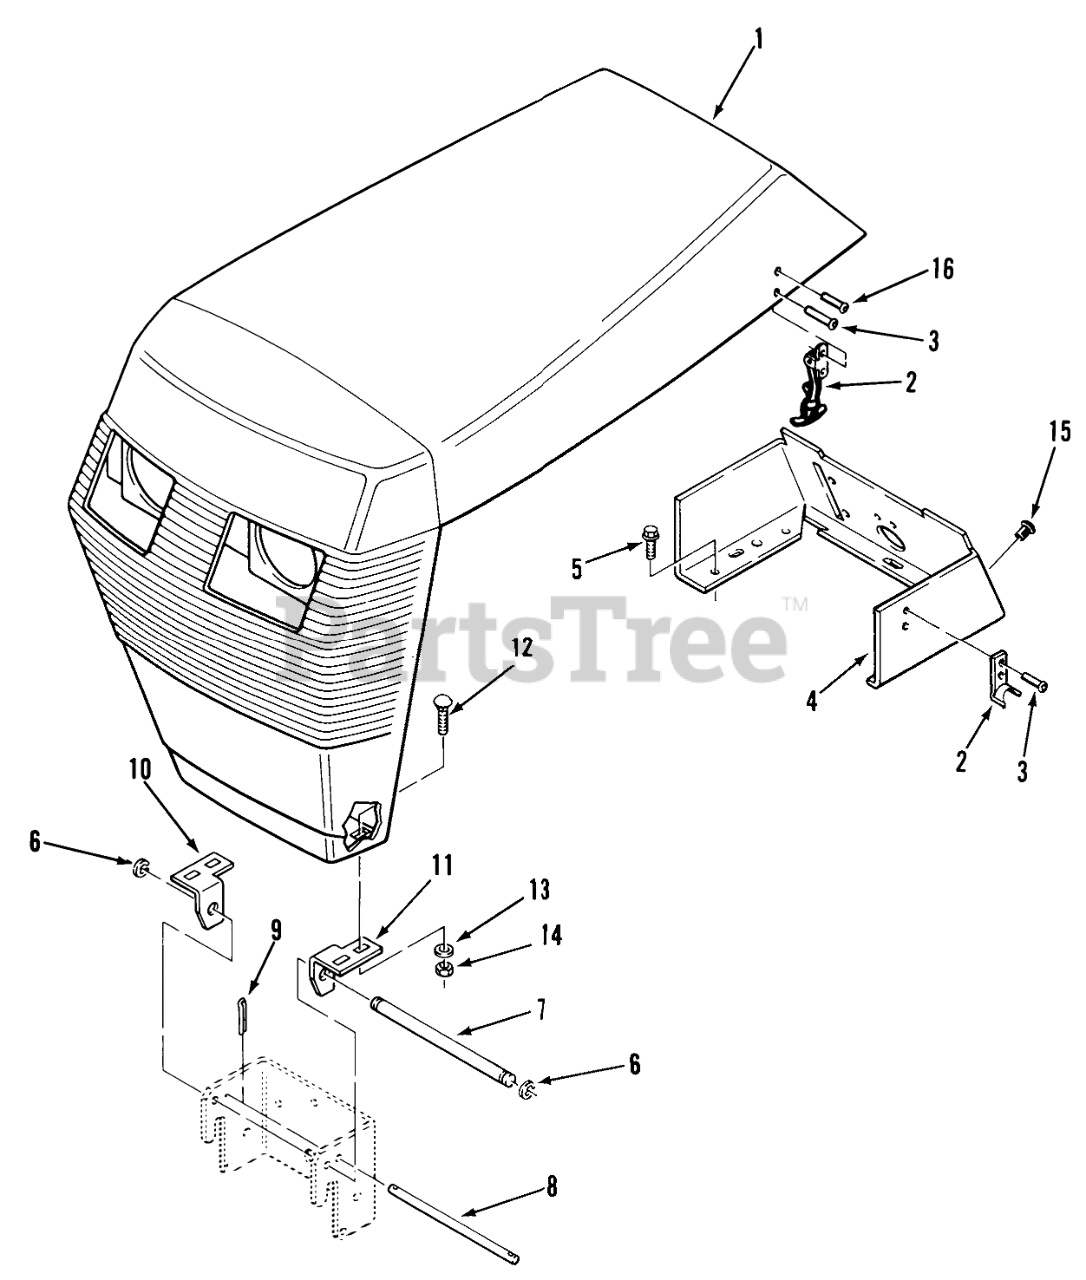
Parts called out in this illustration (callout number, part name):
2	ASSY-FLEX DRAW LATCH
3	RIVET -4
4	Console
5	SCREW
6	RING-RETAINING
7	GRILL PIVOT ROD
8	ROD-HOOD STOP
9	Cotter Pin
10	BRKT-GRILL PIVOT R
11	BRKT-GRILL PIVOT R (NS)
12	Bolt-Carriage
14	Nut
15	NYLON PLUG
16	RIVET
